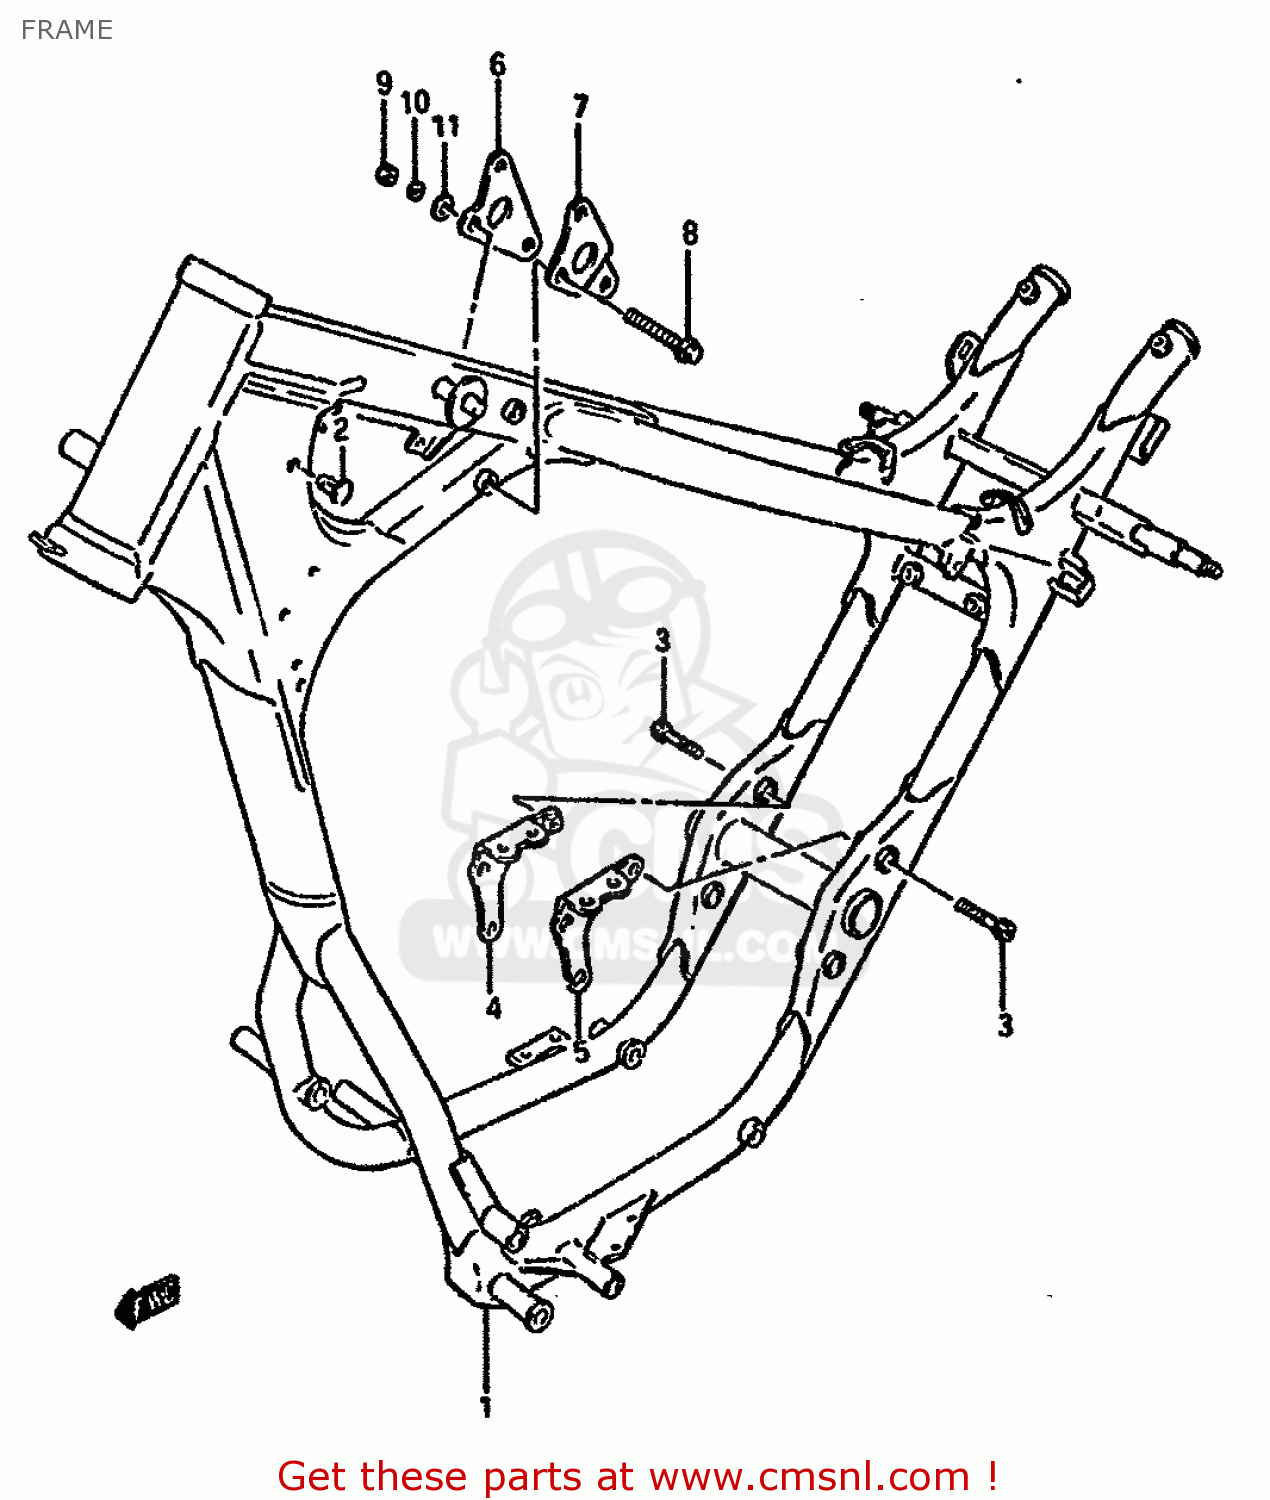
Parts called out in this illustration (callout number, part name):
1	FRAME
2	CLIP
3	BOLT(8X40)
4	PLATE,ENGINE MOUNT NO.4,R
5	PLATE,ENGINE MOUNT NO.4,L
6	PLATE,ENGINE MOUNT NO.5,R
7	PLATE,ENGINE MOUNT NO.5,L
8	BOLT(8X67)
9	NUT,T/F SHIFT LEVER
10	WASHER,LOCK,8.
11	WASHER 8MM
